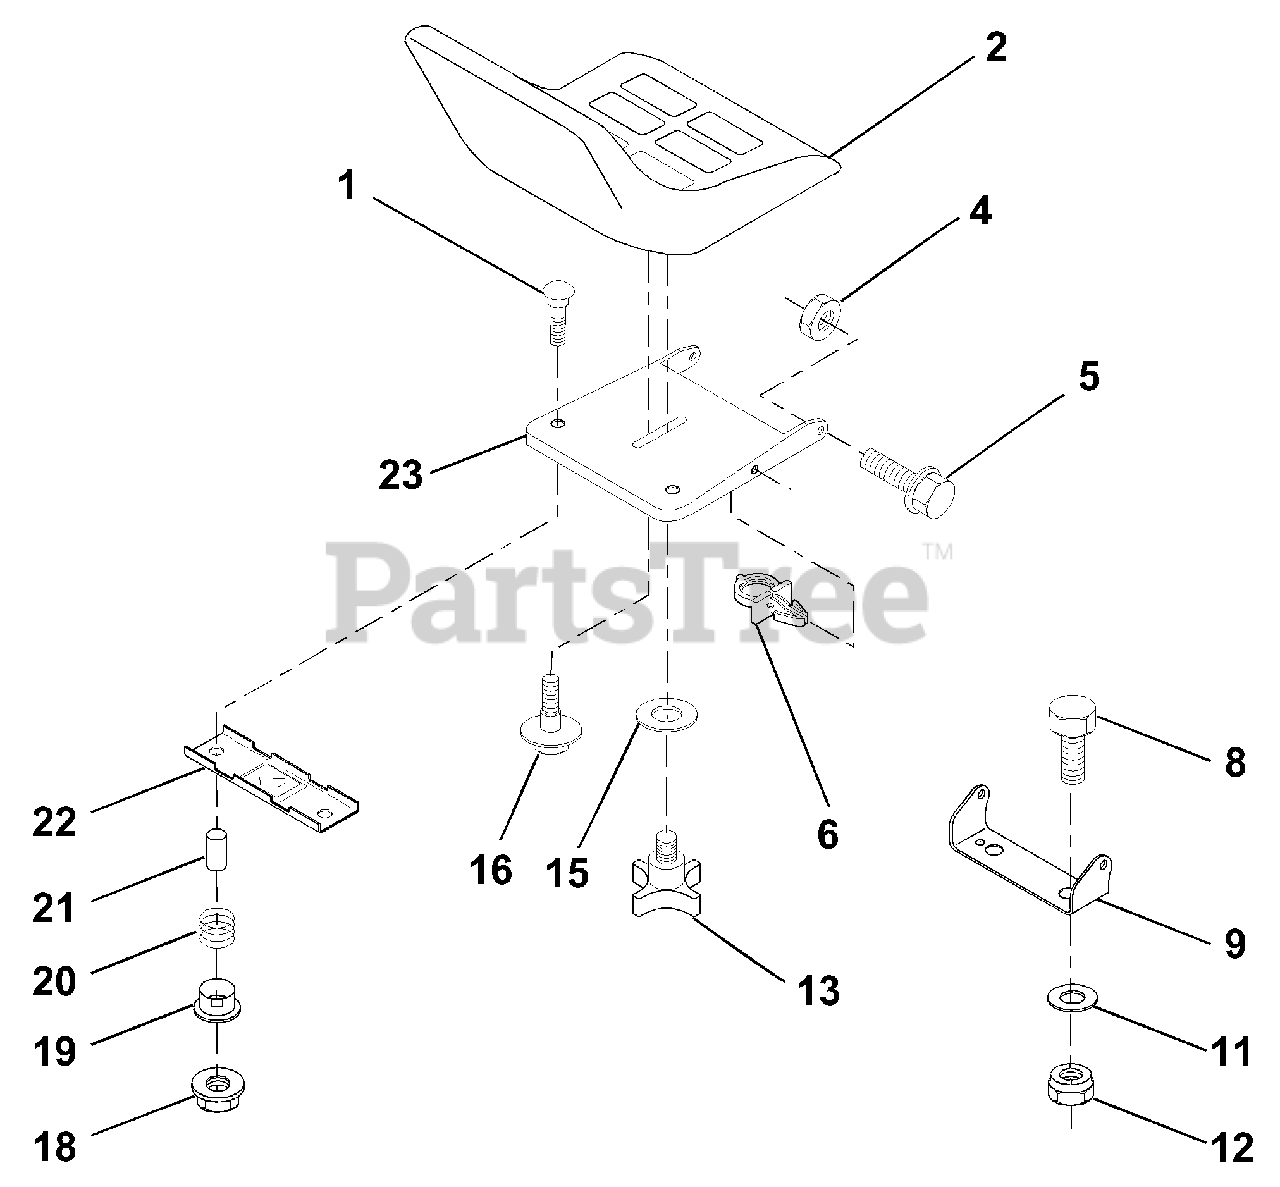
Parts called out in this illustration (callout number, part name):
1	Bolt, Carriage 1/4-20 x 1-3/8
2	Seat
4	Nut, Hex, Lock w/wsh 5/16-18
5	Bolt, Shoulder 5/16-18 UNC
6	Clip, Push-in
8	Bolt, Hex, Fin. 3/8-16 UNC x 1
9	Bracket, Pivot, Seat
11	Washer 12/32 x 2 x 10 Gauge
12	Nut, Hex, Lock Hex w/wsh 3/8-16
13	Knob, Seat
15	Washer 17/32 x 1-3/16 x 12 Gauge
16	Bolt, Shoulder
18	Nut, Hex, Large, Flange Lock
19	Bushing, Snap
20	Spring, Compression
21	Spacer, Split, Large .28 Id. x .96
22	Bracket, Switch Mounting
23	Pan, Seat
